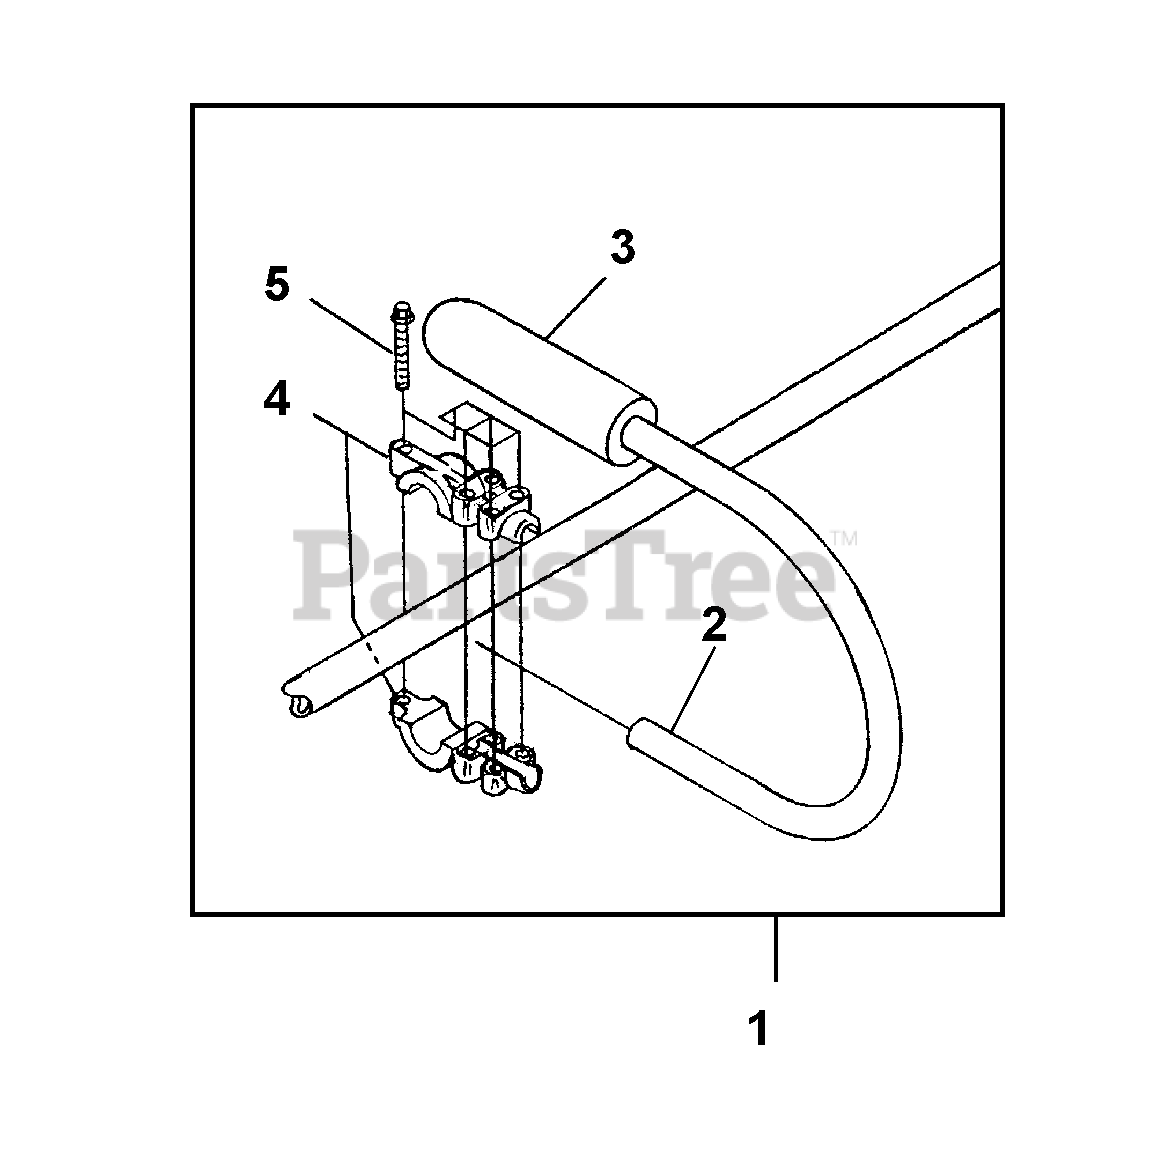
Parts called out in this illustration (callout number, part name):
1	Handle Assembly
2	Handle
3	Grip
4	Bracket Assembly
5	Screw
